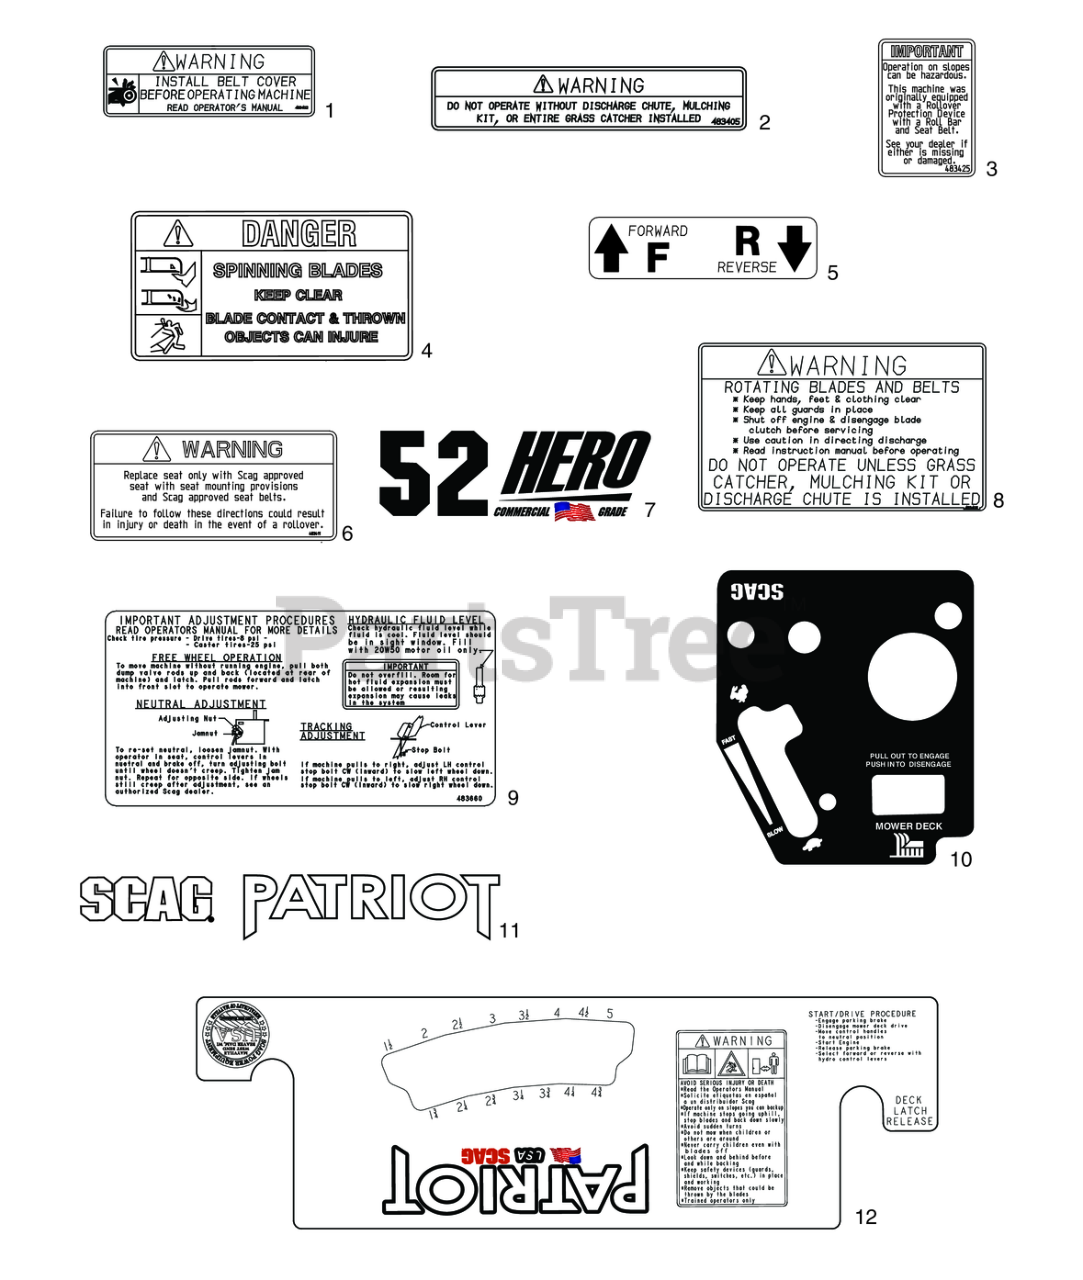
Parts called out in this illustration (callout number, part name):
1	Decal, Warning - Belt Cover
2	Decal, Warning-Discharge
3	Decal, ROPS
4	Decal, Spinning Blades
5	Decal, Traction Control
6	Decal, Seat Replacement
7	Decal, 52H Commercial
8	Decal, Warning - Rotating Blades
9	Decal, Adjustment SFZ
10	Decal, Instrument Panel
11	Decal, Scag RH Fuel Tank
11	Decal, Scag LH Fuel Tank
12	Decal, Cutting Height, (Scag Gold Logo)
